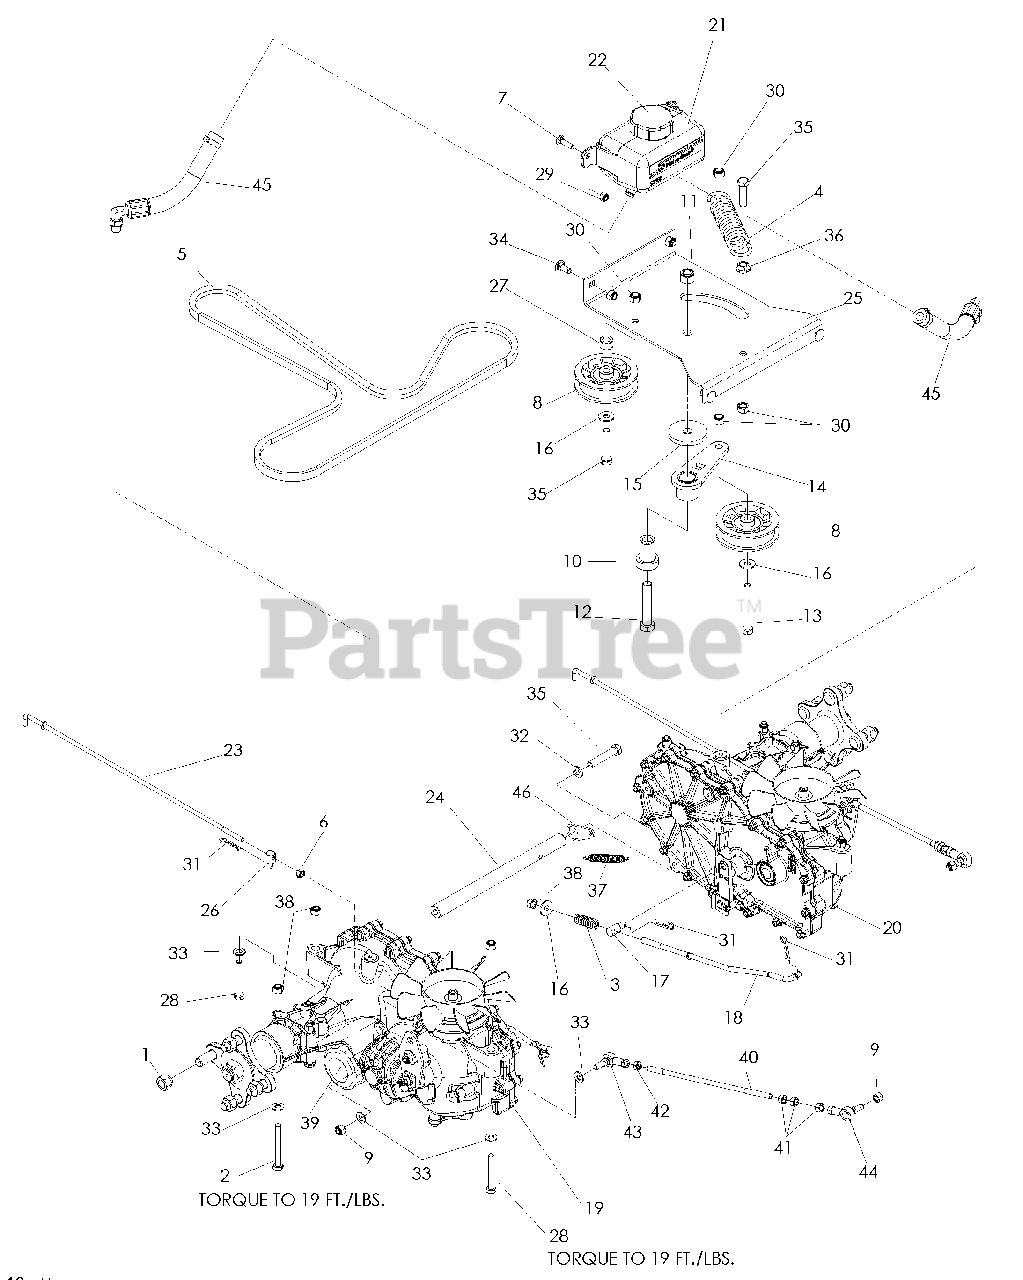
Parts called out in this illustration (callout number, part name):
1	NUT 1/2-20 LUG
2	HCS 5/16-18 x 2 3/4
4	SPRING EXTENSION
5	BELT, PUMP
6	NUT 1/4-28
7	RHSNB 1/4-20 x 1
8	PULLEY, IDLER
9	NUT 5/16 NYLOC
10	SPINDLE, IDLER
11	NUT 1/2-13 NYLOC
12	HCS 1/2-13 x 2 3/4
13	HCS 3/8-16
14	IDLER ARM
15	HEAVY WASHER
16	WASHER 5/16
17	BRAKE SWIVEL
18	BRAKE LINKAGE
19	ZT2800, RIGHT
20	ZT2800, LEFT
21	EXPANSION TANK W/CAP
23	BYPASS LINKAGE
24	2800 CROSS SUPPORT
25	IDLER PULLEY PLATE
26	SWIVEL 1/4-28
28	HCS 5/16-18 x 2 1/4
29	NUT 1/4-20 NYLOC
30	NUT 3/8-16 NYLOC
31	PIN, HAIR .073 x 17/16
32	WASHER 3/8
33	WASHER 5/16 SAE
34	RHSNB 5/16-18 x 3/4
35	HCS 3/8-16 x 2
36	NUT 3/8-16 WHIZLK
38	NUT 5/16-18 NYLOC
39	OIL FILTER
40	DRIVE LINKAGE
41	NUT 5/16-24
42	NUT 5/16-24 LH
43	ROD END, LEFT
44	ROD END, RIGHT
46	TAB, SPRING
